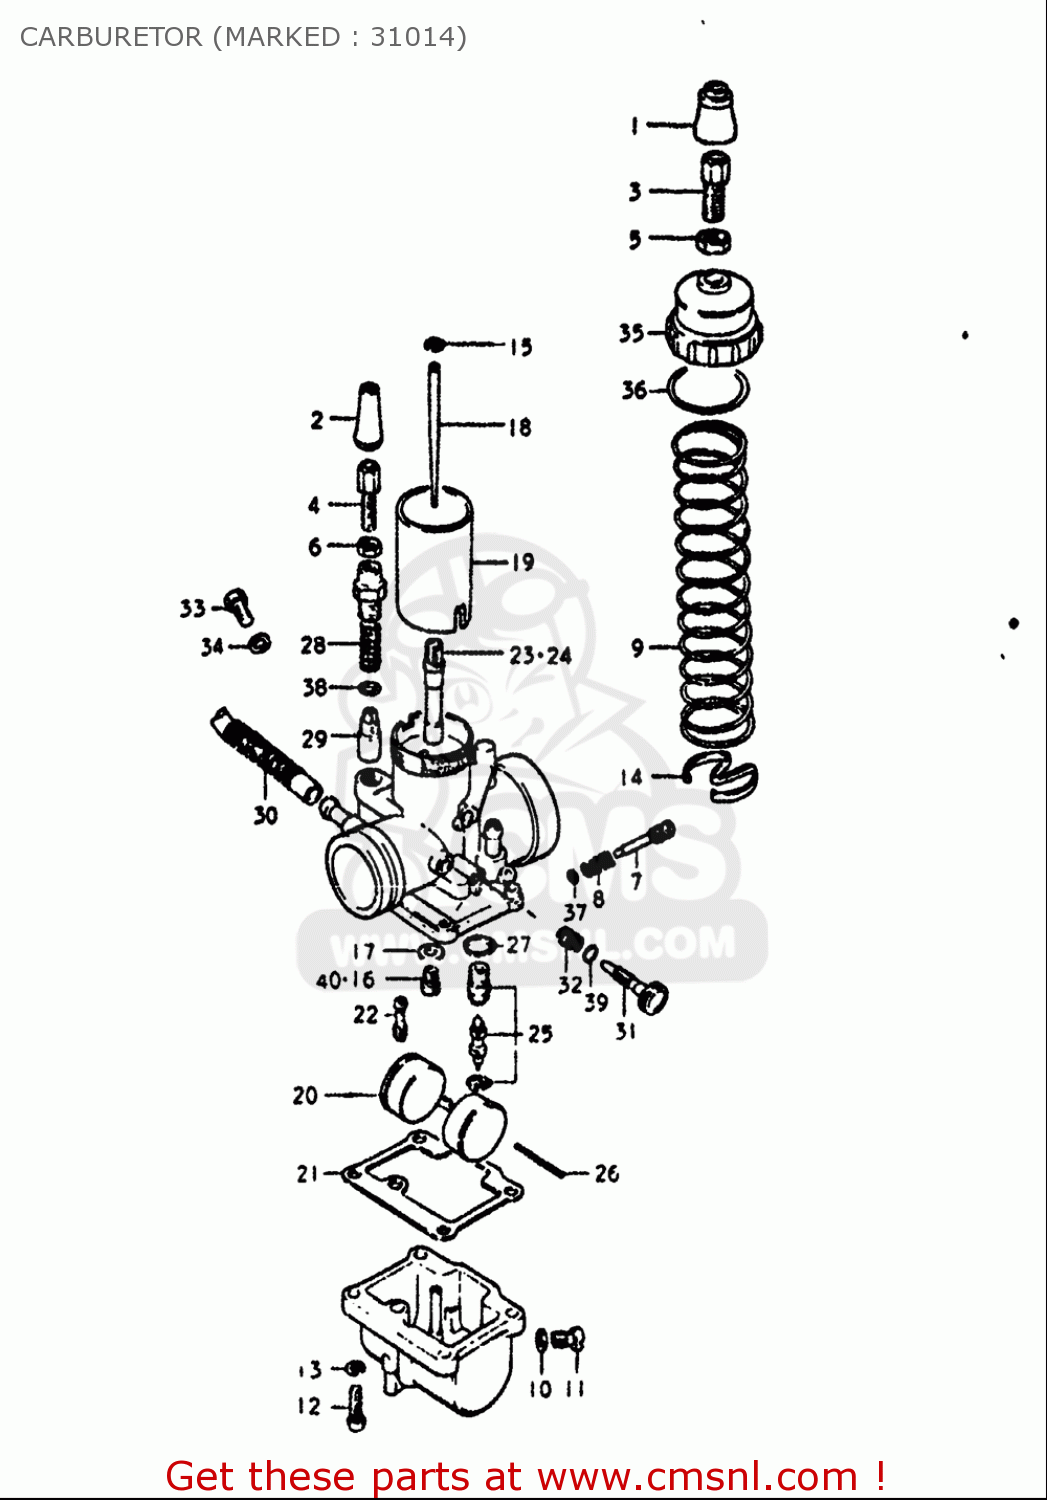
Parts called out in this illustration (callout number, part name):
2	CAP
4	ADJUSTER,CABLE
6	NUT
7	SCREW,PILOT AIR
8	SPRING
10	GASKET,DRAIN,PLUG (NAS)
11	PLUG
12	SCREW 4X16
13	WASHER,LOCK
15	CLIP
16	JET,MAIN
17	WASHER
20	FLOAT
21	GASKET,FLOAT CAHMBER (NAS)
22	JET,PILOT(30)
25	VALVE ASSY,NEEDLE
26	PIN,FLOAT
27	GASKET,MAIN JET HOLDER (NAS)
28	SPRING
29	PLUNGER,STARTER
32	SPRING,THROTTLE SCREW
33	BOLT
34	GASKET,THRO VALVE INSPECTION (NAS)
37	O RING
39	O RING
40	JET,MAIN(105)
